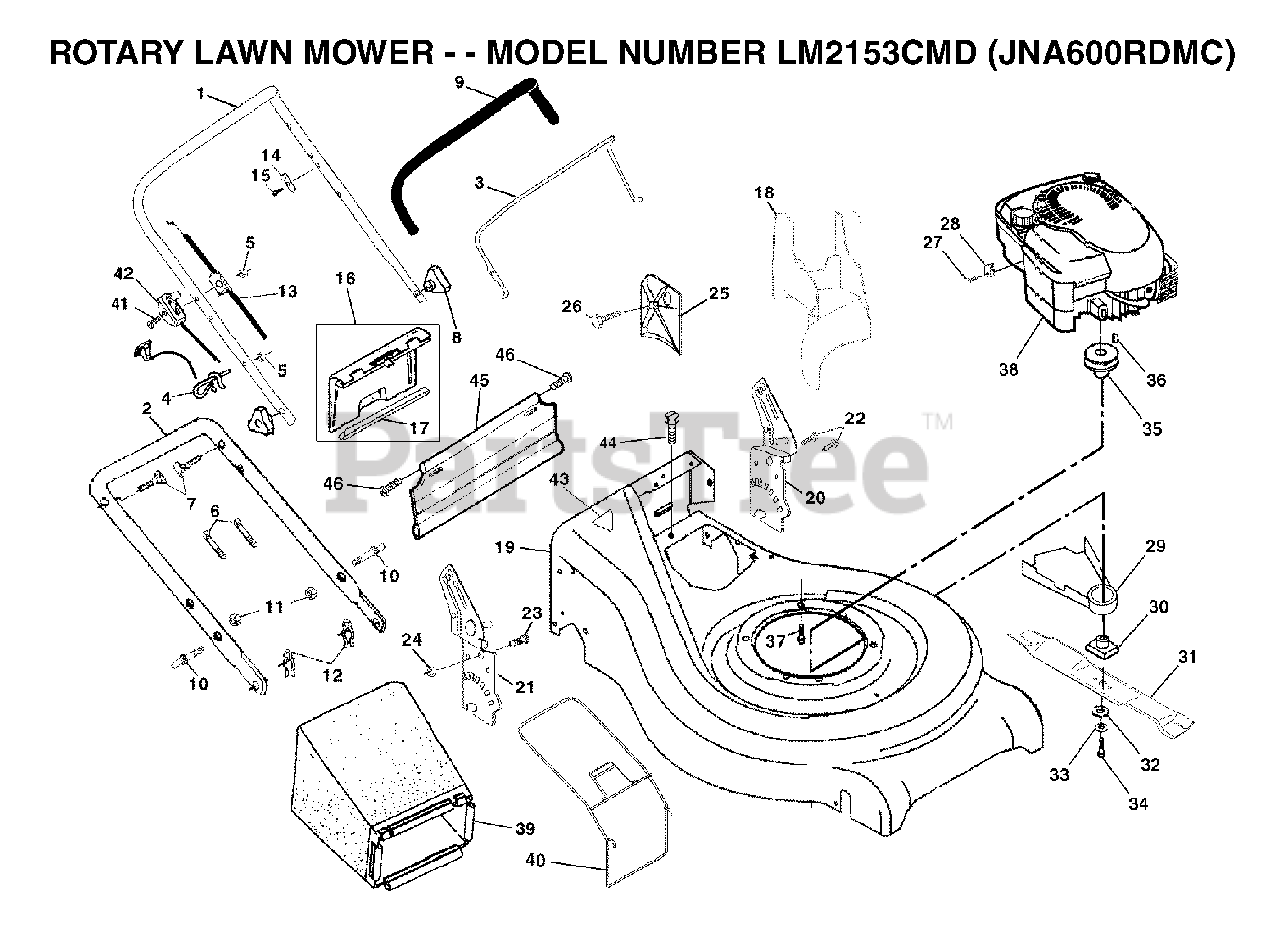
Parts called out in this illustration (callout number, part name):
2	HANDLE
3	CONTROL BAR
4	ROPE, GUIDE
5	NUT
6	TIE GUIDE
7	HANDLE BOLT
9	GRIP.HANDLE.FOAM
10	BOLT
11	NUT
12	HAIRPIN COTTER
13	ENGINE ZONE CONTROL
14	BRACKET UPSTOP
15	SCREW.HEX.HEAD.WASHER.10-16
16	REAR DOOR KIT
17	SEAL, DOOR
18	MULCHER PLUG
20	.RACKET
22	SELF-TAPPING SCREW 5/16-18X3/4
23	BOLT, HEX HEAD 5/16-18
24	NUT.71038.31-18.HEX.NYLOCK
25	CLIPPING DEFLECTOR
27	SCREW.HEX.HEAD.WASHER.10-16
28	CABLE CLAMP(ENGINE)
29	SHIELD.DEBRIS.21.RWGD.EZ
30	RP BLADE ADAPTOR
31	BLADE
32	WASHER,HARDEN
33	LOCKWASHER
34	SCREW, HEX HD 3/8-24 X 1-3/8
35	ENGINE.PULLEY.FWG
36	HI PRO KEY PM
37	BOLT 3/8-16X1-1/8
40	FRAME.GRASS.CATCHER.21.RGD
41	SCREW 1/4-20 X 2.12
42	CONTRL.THROTTLE.
45	REAR SKIRT
46	HINGE SCREW
